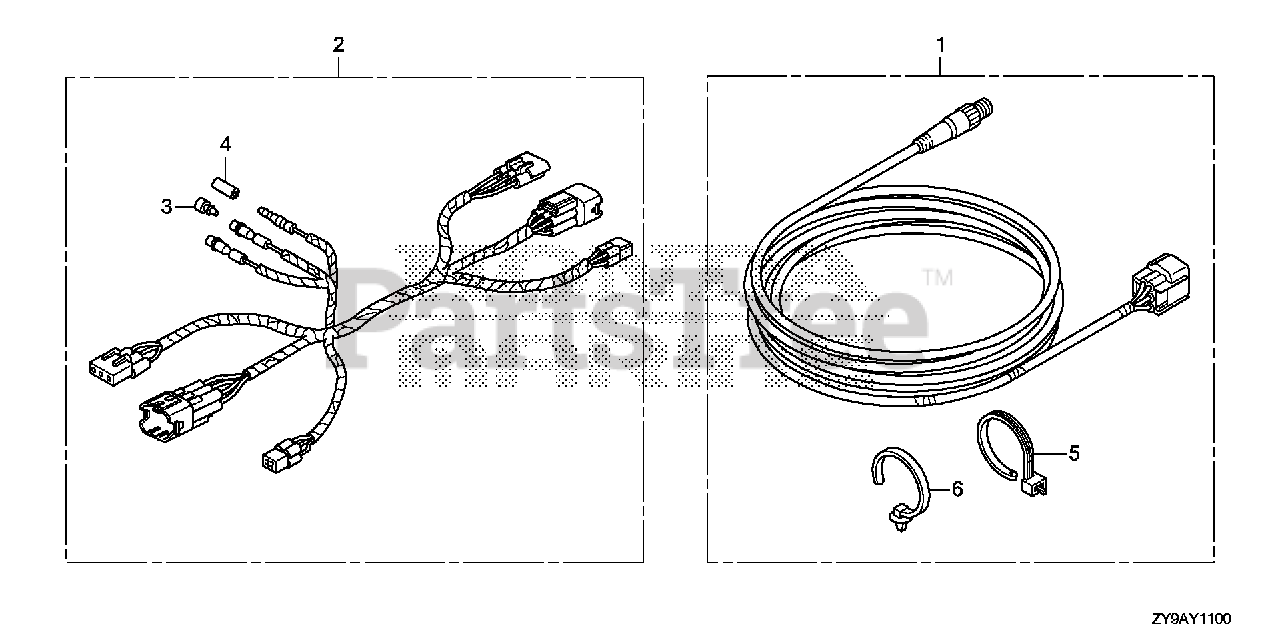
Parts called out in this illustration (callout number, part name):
1	KIT, CABLE (6FT) (NMEA)
2	HARNESS ASSY., REMOTE CONTROL SUB (ENGINE NO.)
3	PLUG, CONNECTOR (INNER) (TROLLING CONTROL)
4	PLUG, CONNECTOR (OUTER) (ENGINE NO.)
5	TIE, CABLE
6	CLIP, HARNESS BAND (155.3MM) (BLACK)
